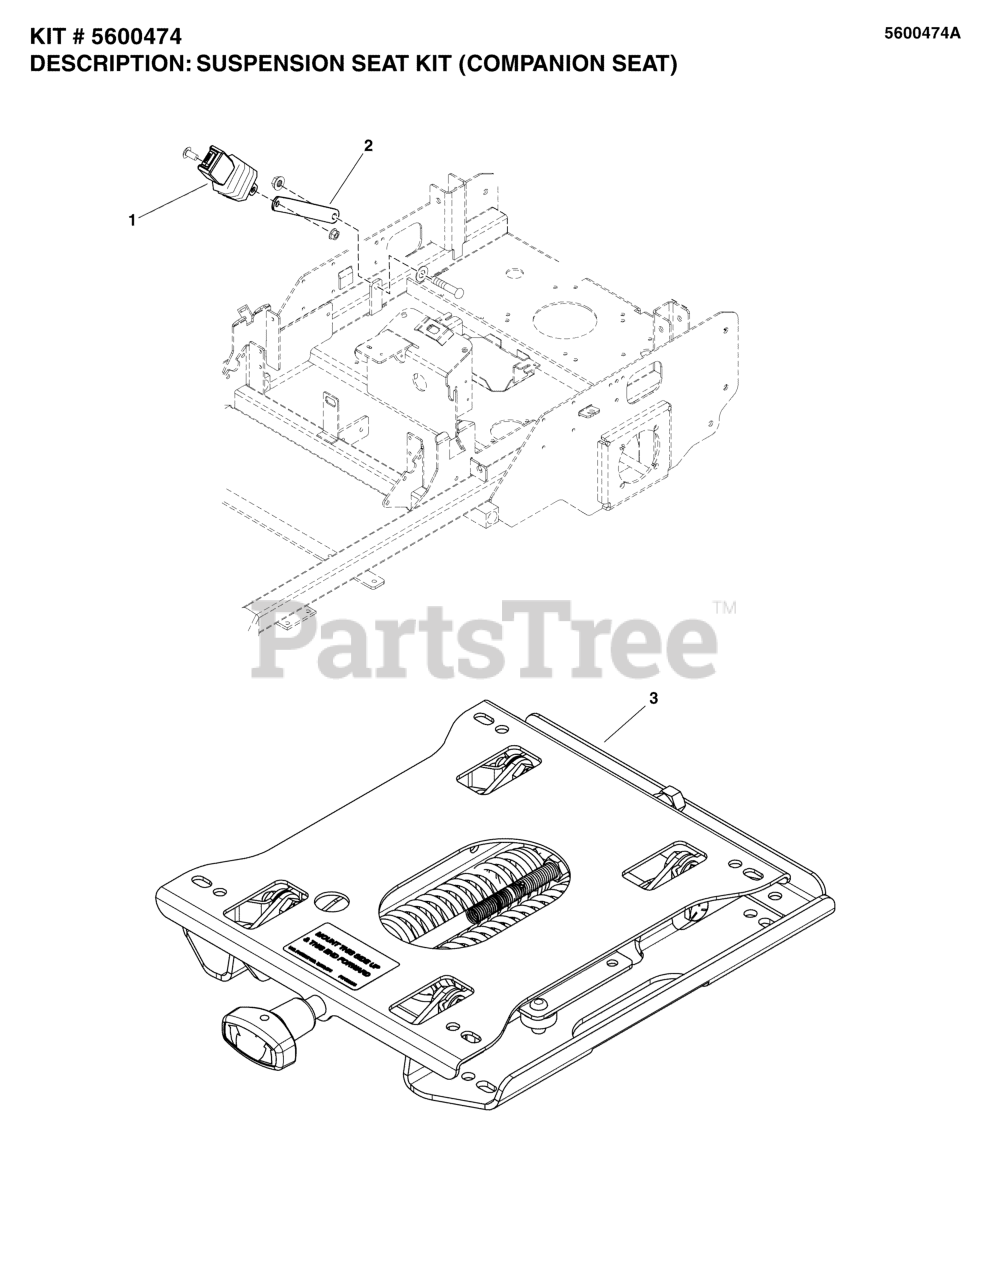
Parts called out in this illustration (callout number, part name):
1	SEAT BELT ASSM, RETRACTOR + SUP SLEEVE
2	EXTENSION, SEAT BELT - BLK
3	SUSPENSION, 1110EVC, COMPANION
